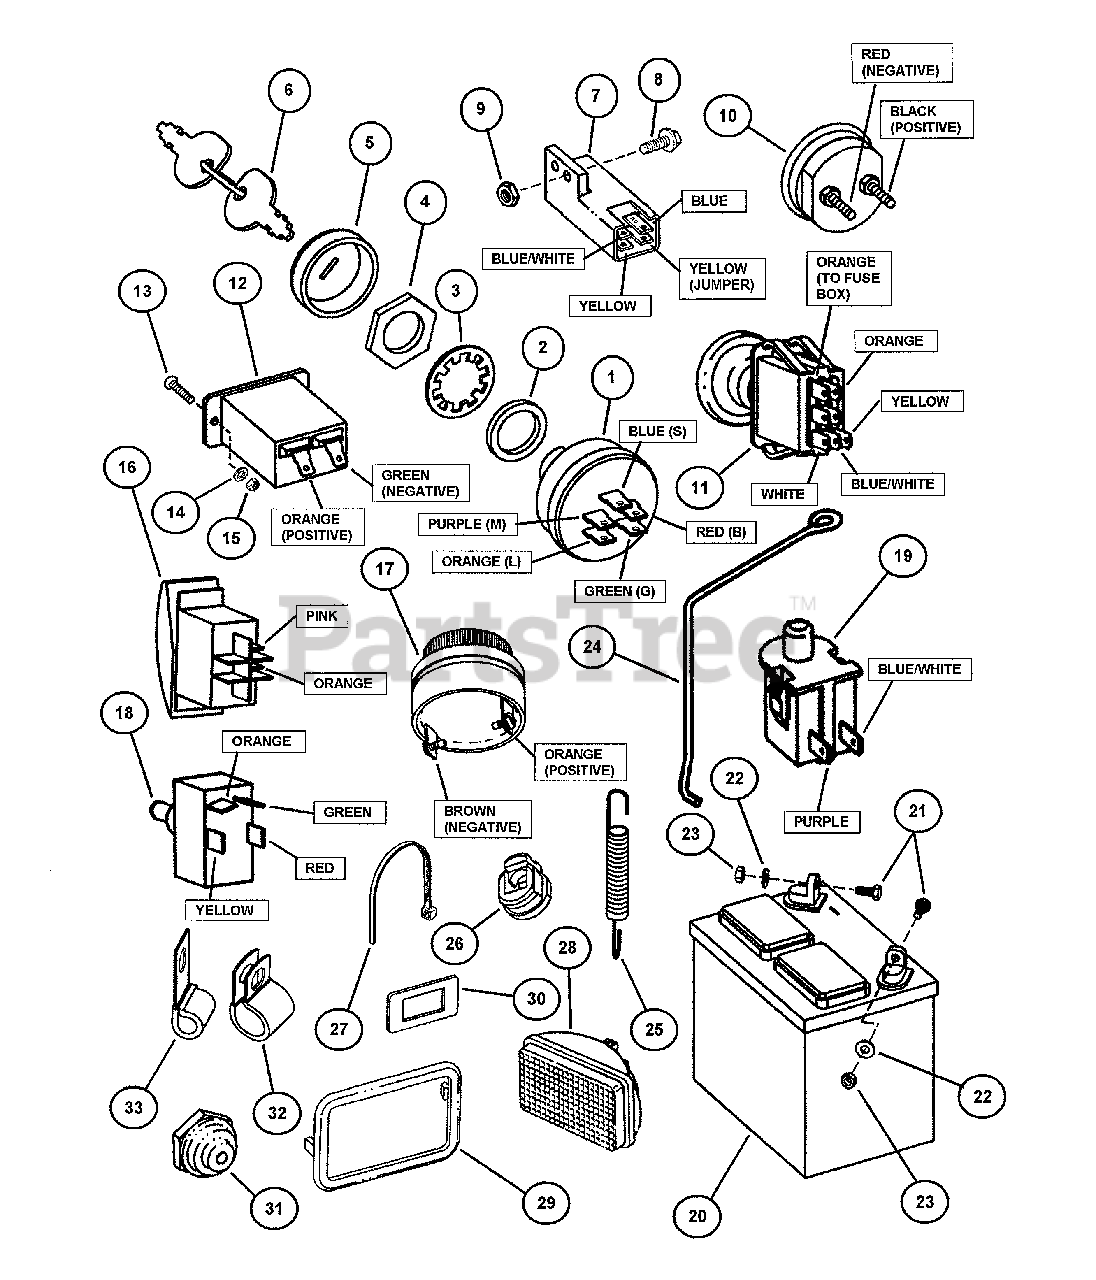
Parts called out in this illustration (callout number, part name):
1	KEYSWITCH, Ignition-Afterfire Solenoid
2	SPACER, 5/8"
3	WASHER, 5/8" Internal Tooth Lock
4	NUT, 5/8-32 Hex
5	BEZEL
6	KEY, and Ring
7	SWITCH, DPDT
8	SCREW, #10-32 x 5/8" Hex Wash. Hd. Machine, Grade 5
9	NUT, #10-32 Hex Nyloc
10	ASSEMBLY, Ammeter and Clamp
11	SWITCH, PTO
12	HOUR METER, D.C. Series 1500
13	SCREW, #6-32 Round Head Machine
14	WASHER, #6 Internal Tooth Lock
15	NUT, #6-32 Hex
16	SWITCH, Lights
17	BUZZER, Pulsing
18	SWITCH, Self Centering, Deck Lift
19	SWITCH, Seat NC
20	BATTERY, 11 Plate-380CCA
21	SCREW, 1/4-20 x 5/8", Hex Head Cap, Grade 5
22	WASHER, .28 I.D. x .63 O.D. x .06 Flat
23	NUT, 1/4-20 Hex Center Lock, Grade 5 or B
24	BRACKET, Battery
25	SPRING, Battery
26	STRAIN RELIEF, Wire
27	CABLE TIE, 7"
28	HEAD LIGHT
29	BEZEL, Headlight
30	SPACER, PTO Switch
31	SEAL, Switch
32	CLIP, Harness
33	CLIP, Open J, 3/8" Cushioned
